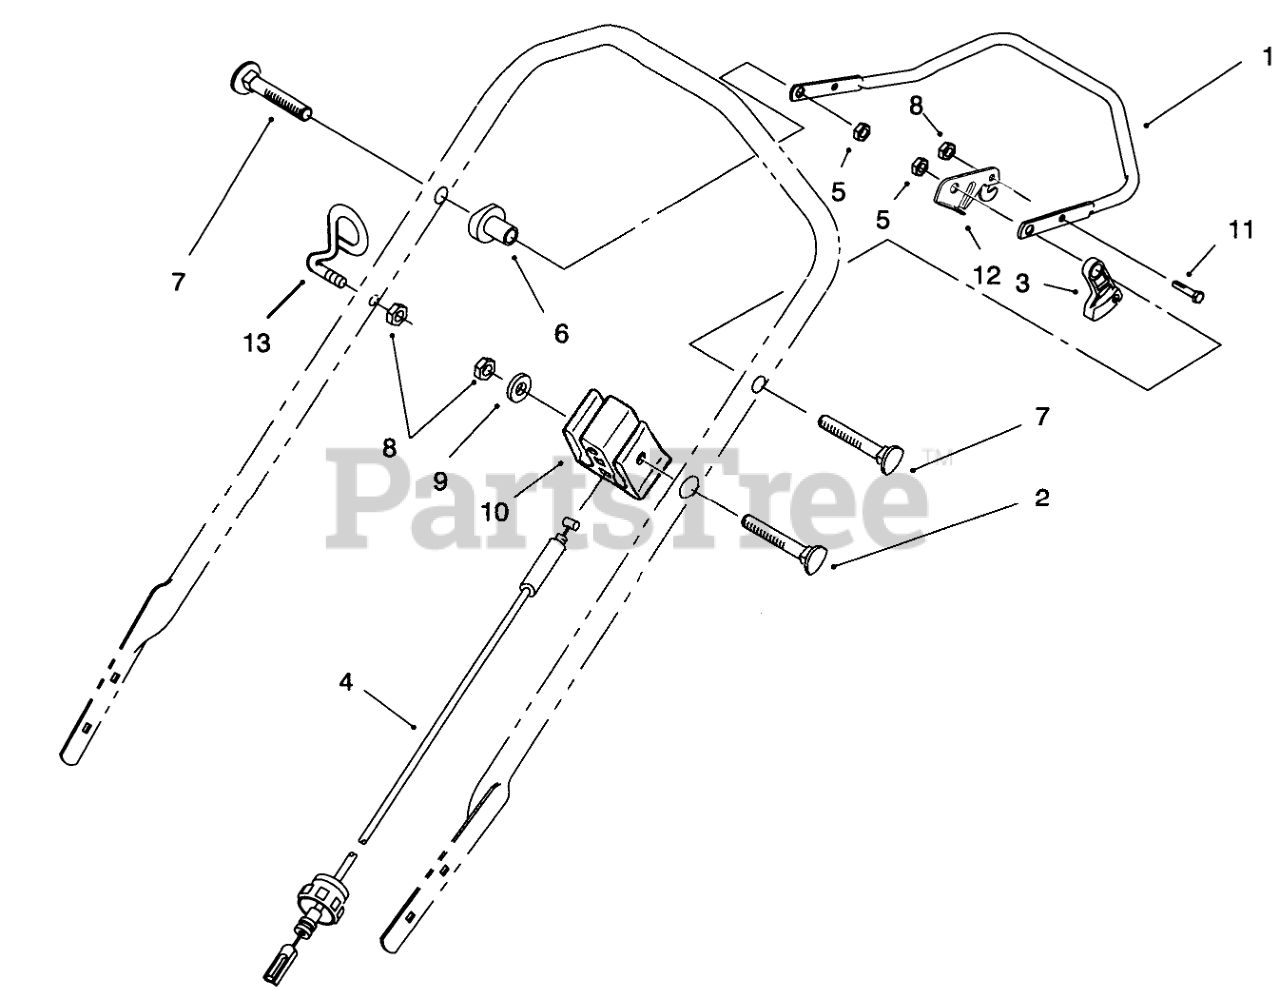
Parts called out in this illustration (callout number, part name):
1	Bar-Control
2	HANDLE SCREW
3	LEVER-TRACTION
4	CABLE-TRACTION
5	NUT-LOCK, NI
6	SPACER-SUPPORT
7	5/16-18 X 2 HNDLE SCREW
8	NUT-LOCK, NI
9	WASHER-FLAT
10	SUPPORT-CABLE
11	SCREW-HH
12	LEVER-CONTROL
13	ROPE GUIDE
